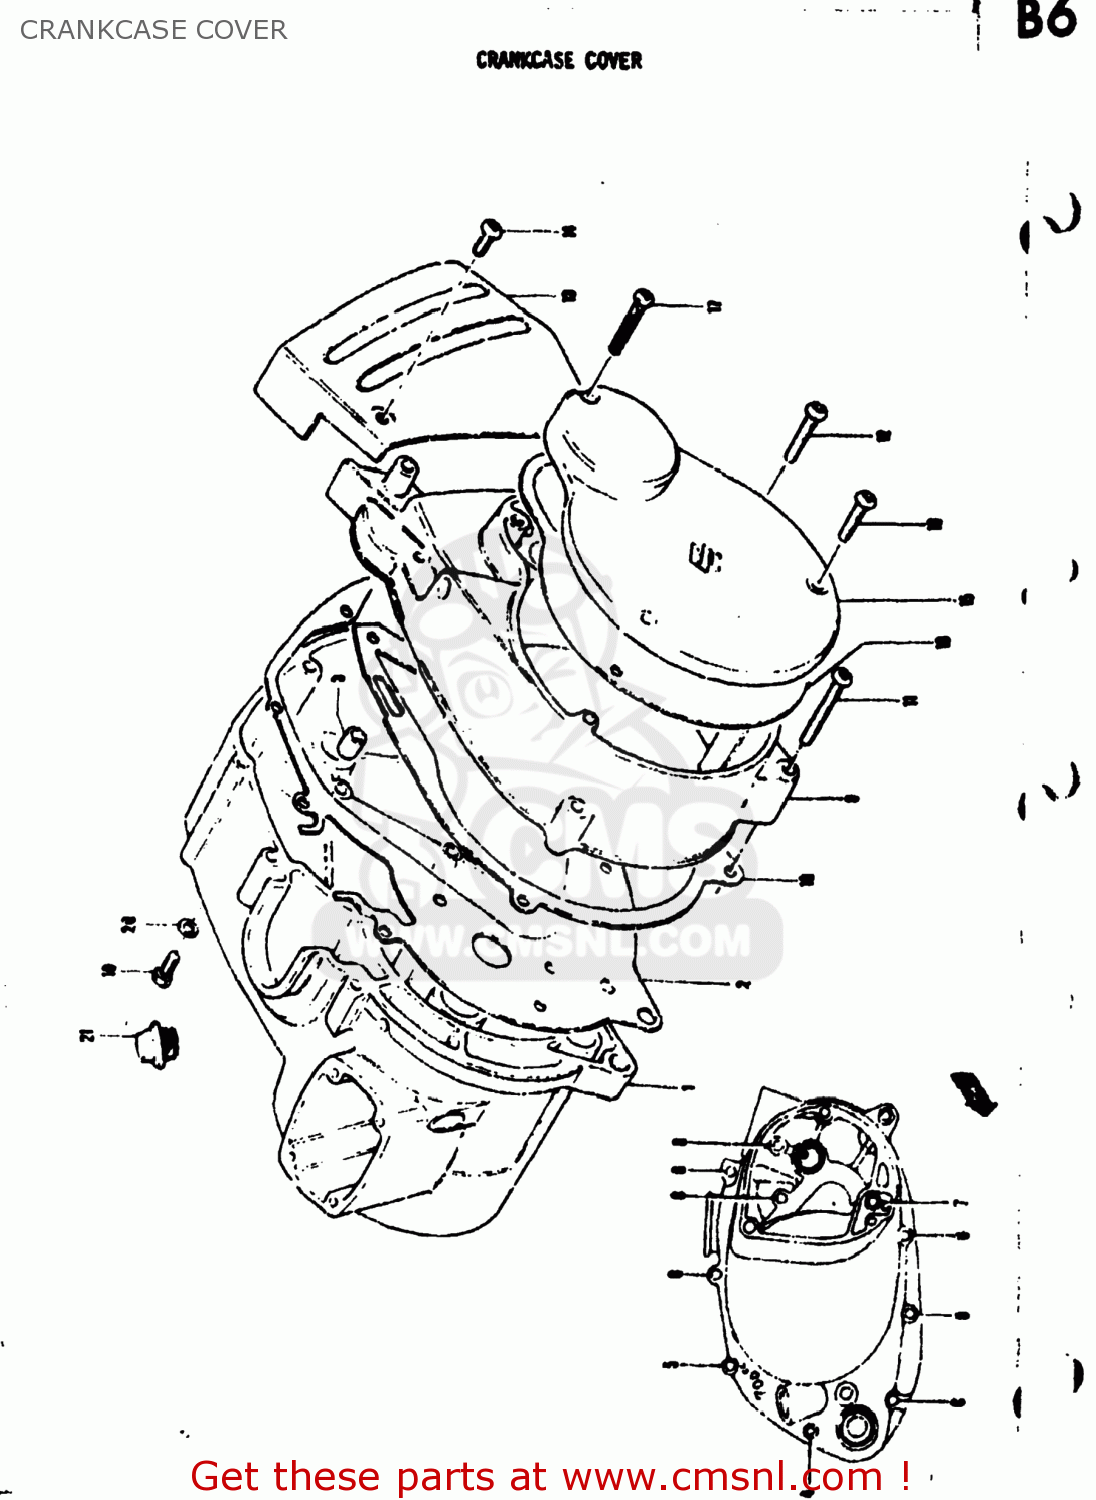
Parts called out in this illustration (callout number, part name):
1	COVER,CLUTCH
2	GASKET,CLUTCH COVER (MCA)
3	PIN
4	SCREW 6X70
5	SCREW
6	SCREW (6X35)
7	SCHROEF 5X80
8	SCREW
9	COVER
10	GASKET,MAGNETO COVER (NAS)
11	SCREW (6X35)
12	SCREW
13	COVER,SPROCKET
14	SCREW
15	COVER,SIGNAL GENERATOR
16	GASKET (MCA)
17	SCREW
18	SCREW
19	SCREW(6X10)
20	GASKET(6.2X11X1) (NAS)
21	PLUG,OIL FILTER
